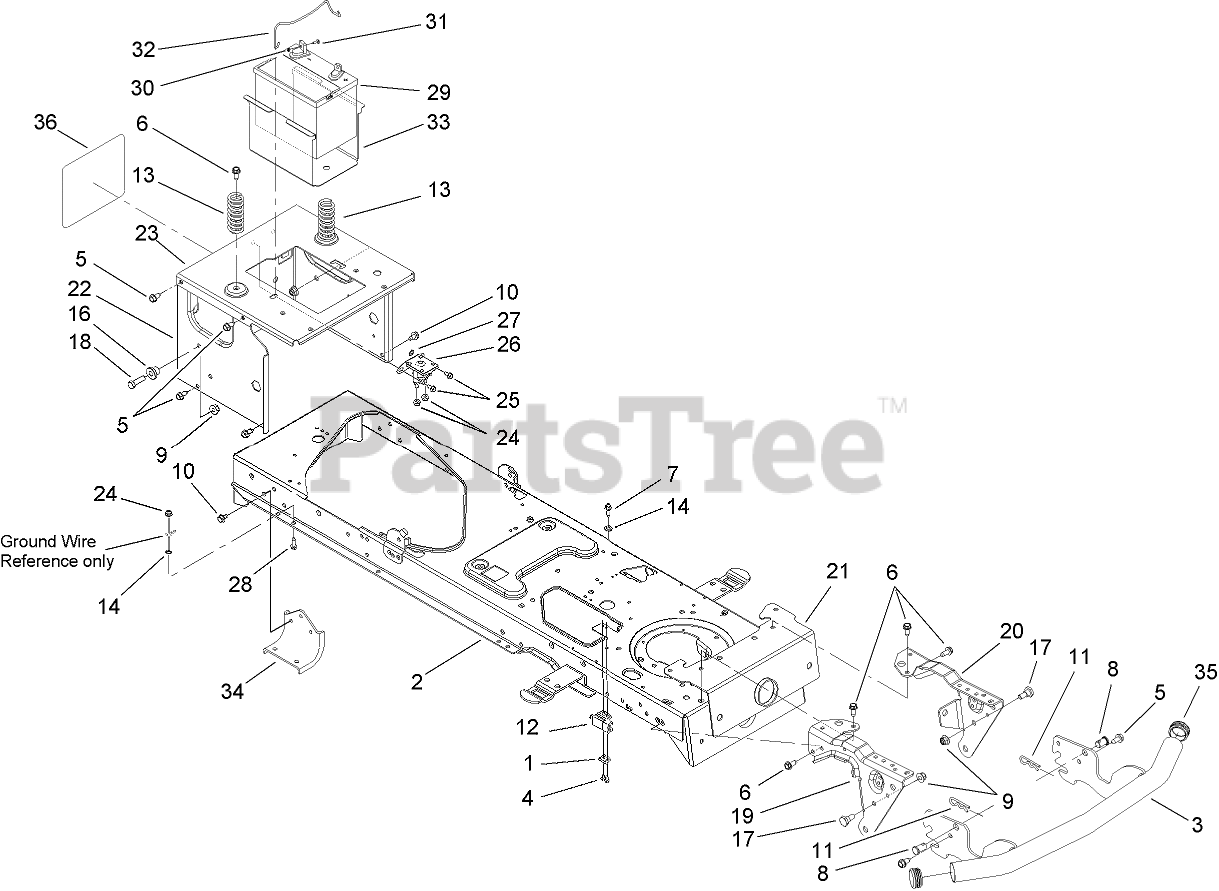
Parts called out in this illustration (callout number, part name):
1	PLATE-SWITCH
2	LOWER FRAME ASM
3	BUMPER ASM
4	SCREW-TAP
5	SCREW-HH, TAP
6	SCREW-HWH
7	SCREW-HWH
8	PIN-BRACKET, LIFT
9	NUT-LOCK, FLANGE
10	SCREW-TAP
11	PIN-HAIR
12	SWITCH-INTERLOCK
13	SPRING-COMPRESSION
14	WASHER-LOCK, EXTERNAL
16	SPACER-SHOULDER
17	BOLT-SHOULDER
18	SCREW-HH
19	BRACKET-PIVOT, SUPPORT
20	BRACKET-PIVOT, SUPPORT
21	BRACKET-PIVOT, BAR
22	FRAME-UPPER
23	BRACKET-FRAME, SEAT
24	NUT-LOCK, FLANGE
25	SCREW-HWHTF
26	SOLENOID-12V, 2 Post 1 Tab
27	WASHER-LOCK, EXTERNAL
28	SCREW-TAP
29	BATTERY-245, CCA (DRY FLAT TOP)
30	NUT-SEMS
31	BOLT-CARR
32	ROD-HOLDDOWN, BATTERY
33	TRAY-BATTERY
34	BRACKET-AXLE
35	BUMPER-CAP
36	DECAL-TORO
